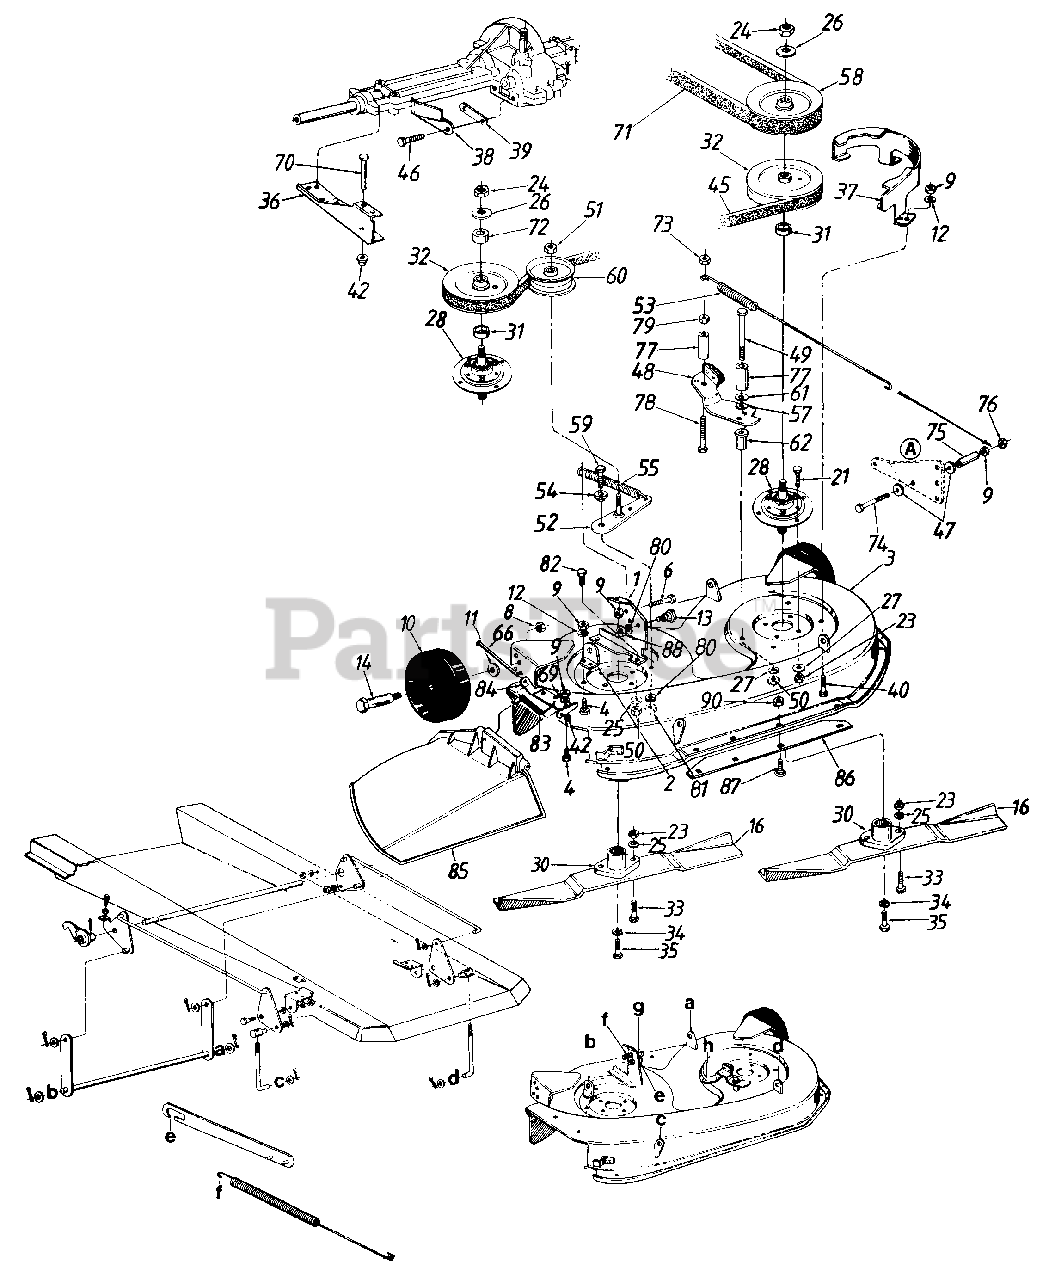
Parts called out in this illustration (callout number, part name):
1	Deck Disengagement Brkt.
2	Rear Deck Brkt.--R.H.
3	38" Deck Ass'y.
4	Hex Bolt 1/4-20 x .62" Lg.
6	Hex Wash. Hd. Scr. 1/4-20 x 1.5" Lg.
8	Hex L-Nut 3/8-16 Thd.
9	Hex Nut 1/4-20 Thd.
10	Deck Wheel
11	Bell-Wash. .380 I.D. x .88
12	L-Wash. 1/4 I.D.
13	Shld. Bolt .500 Dia. x .336" Lg.
14	Shld. Bolt .498 Dia. x 1.53" Lg.
16	High-Lift Blade
21	Hex Bolt 5/16-24 x .75" Lg.
23	Hex Nut 5/16-24 Thd.
24	Hex Jam Nut 5/8-18 Thd.
25	L-Wash. 5/16" I.D.
26	L-Wash. 5/8" I.D.
27	Bell-Wash. .345 I.D. x .88
28	Blade Spindle Ass'y. Comp.
30	Blade Adapter
32	5" Dia. Pulley
33	Hex Bolt 5/16-24 x 1.0" Lg. (Special)
34	L-Wash. 3/8" I.D. H.D.
35	Hex Bolt 3/8-24 x 1.0" Lg.
39	Belt Guard Spacer
42	Cap Speed Nut 1/4" Rod
45	V-Belt
46	Hex TT-Tap Scr. 1/4-20 x .75" Lg.
47	Fl-Wash. 1/4" I.D.
48	Deck Brake Brkt. Ass'y.
49	Hex Bolt 5/16-18 x 3.25" Lg.
50	Hex Nut 5/16-18 Thd.
51	Hex L-Nut 3/8-24 Thd.
52	Idler Brkt. Ass'y.
53	Extension Spring 17.75" Lg.
54	Shoulder Spacer .625" I.D.
55	Extension Spring 7 3/4" Lg.
57	Wave Washer .53" I.D. x .78" O.D.
58	5" Dia. Pulley
59	Hex Bolt 3/8-16 x 1" Lg.
60	Flat Idler Pulley
61	Shld. Spacer .51" I.D. x .27" Lg.
62	Spacer.31" I.D. x 1.46" Lg.
66	Hinge Pin 1/4" Dia. x 6.75" Lg.
69	Bell-Wash. 1/4" I.D.
70	Pin .25" Dia. x 2.5" Lg.
71	V-Belt
73	Hex L-Nut 1/4-28 Thd.
74	Hex Bolt 1/4-20 x 2.5" Lg.
75	Spacer 1/4" I.D. x 3/8" O.D.
76	Hex L-Nut 1/4-20 Thd.
77	Spacer 5/16" I.D. x 1/2" O.D.
78	Hex Bolt 1/4-28 x 1.75" Lg.
79	Hex Nut 1/4-28 Thd.
80	L-Wash. 3/8" 1 .D.
81	Hex Nut 3/8-16 Thd.
82	Hex Bolt 5/16-18 x .75" Lg.
83	Torsion Spring
84	Hinge Mtg. Brkt.
85	Chute Ass'y. Comp.
88	Hex Nut 3/8-16 Thd.
90	Hex Sems Nut 1/4-20 Thd.
